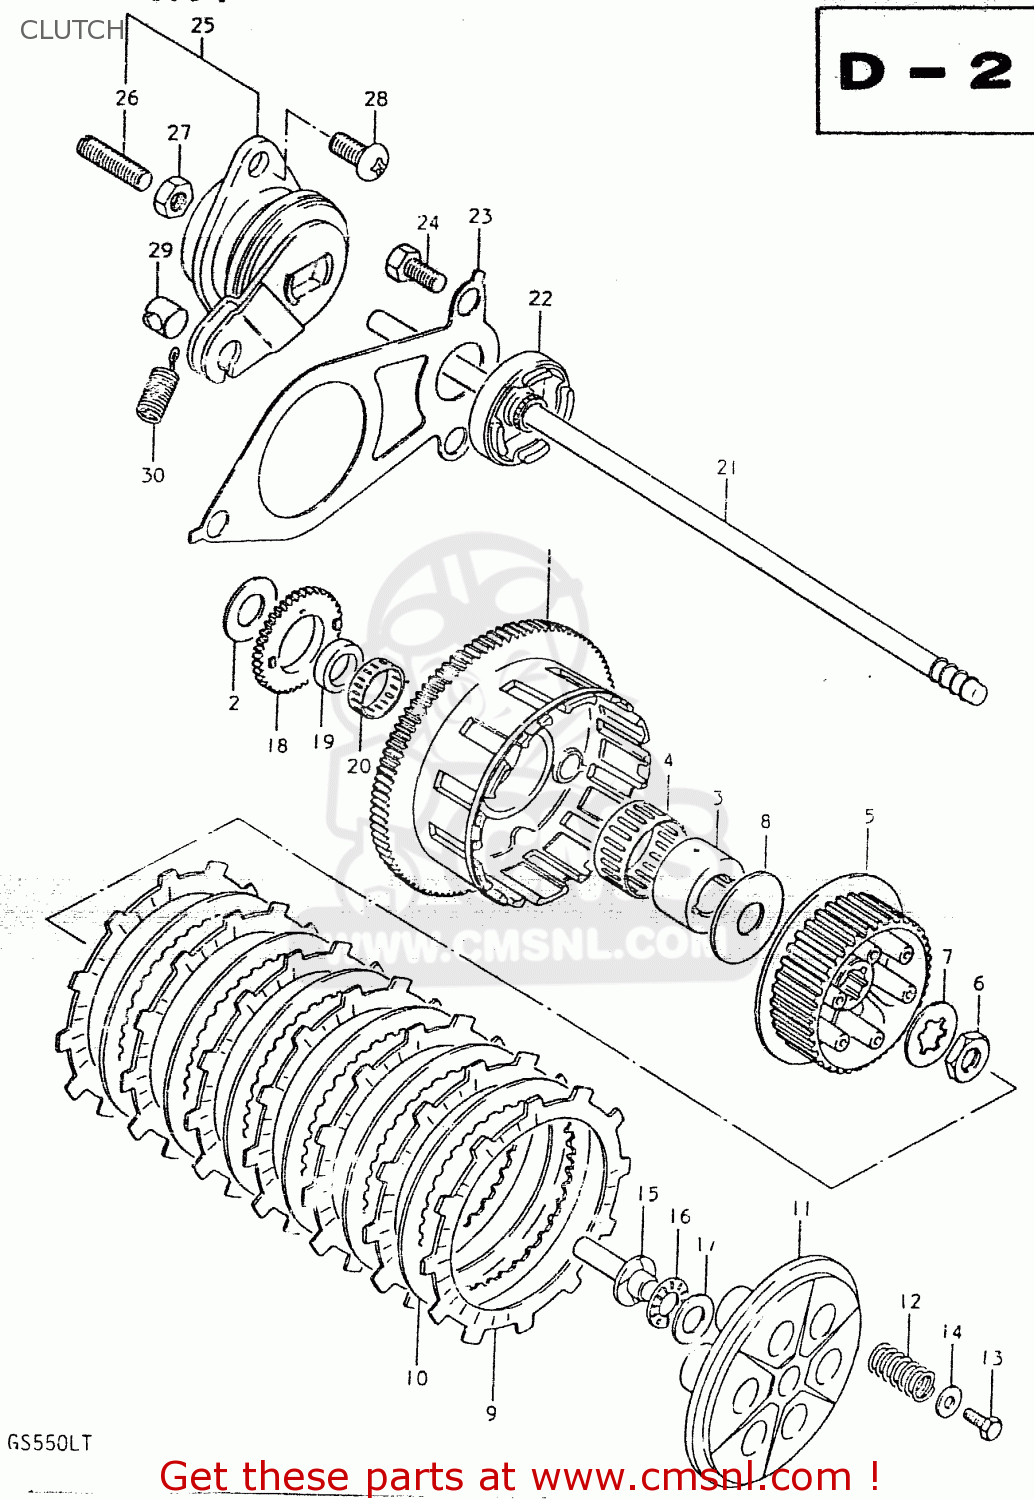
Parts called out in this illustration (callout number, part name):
1	GEAR ASSEMBLY,PRIMARY DRIVE NT:87
2	WASHER
3	SPACER,PRIMARY DRIVEN
4	BEARING
5	HUB,CLUTCH SLEEVE
6	NUT
7	WASHER,LOCK
8	WASHER(25X66X3.5)
9	PLATE,CLUTCH DRIVE (NAS)
10	PLATE,CLUTCH DRIVEN (NAS)
11	DISC,CLUTCH PRESSURE
12	SPRING
13	BOLT, UPPER
14	WASHER
15	PIECE,CLUTCH PUSH
16	BEARING(15X28X2)
17	WASHER
18	GEAR,ENG OIL PUMP DRIVE(NT:38)
19	SPACER,OIL PUMP DRIVE GEAR
20	BEARING(36X40X10)
21	ROD,CLUTCH PUSH
22	OIL SEAL
23	PLATE,CLUTCH PUSH ROD
24	BOLT
25	SCREW ASSEMBLY,CLUTCH RELEASE
26	SCREW
27	NUT 6MM
28	SCREW 6X12
29	PIECE,RELEASE ARM END
30	SPRING
